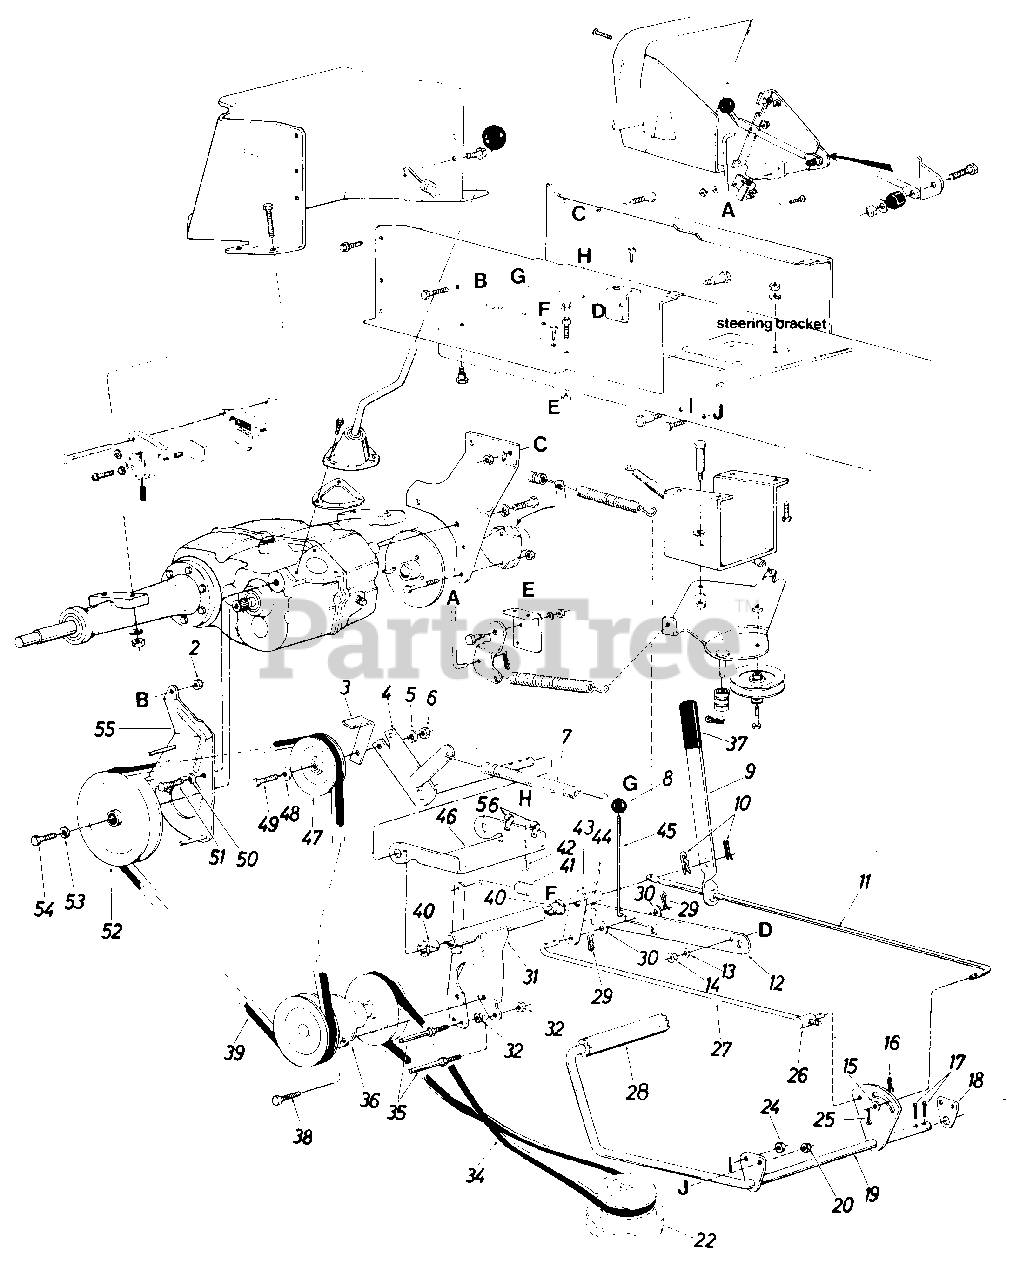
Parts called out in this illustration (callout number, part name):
2	Hex L-Nut 3/8-16 Thd.
5	L-Wash. 3/8" Scr.
6	Hex Nut 3/8-16 Thd.
7	Ext. Spring
8	Knob
9	Hand Brake Lever
10	Hairpin Cotter 3/8" Rod
11	Brake Rod
12	Parking Brake Cam
13	Fl-Wash. 5/16" Scr.
14	Hex Nut 5/16-18 Thd.
15	Fl-Wash. 5/16" Scr.
16	Hairpin Cotter 3/8" Rod
17	Cotter Pin 1/8" Dia. x 1.00" Lg.
18	Clutch Rod Brg. Brkt.
19	Clutch Brake Pedal Ass'y.
20	Hex Cent. L-Nut 3/8-16 Thd.
22	Engine Pulley 4.75 & 5.56
24	Hex Cent. L-Nut 3/8-16 Thd.
25	Cotter Pin 3/32" Dia. x .75" Lg.
26	Pivot Bushing
27	Brake Cam Rod
28	Foot Pad
29	Hairpin Cotter 3/8" Rod
30	Fl-Wash. 3/8" I.D. x 1.00" O.D. x .030
31	Jack Shaft Mtg. Brkt. Ass'y.
32	Hex Top L-Nut 3/8-16 Thd.
34	"V"-Belt 1/2 x 59" Lg. (Polyester)
35	Stud 3/8-16 x 3.62" Lg. Special
36	Jack Shaft Ass'y.
37	Flat Grip
38	Hex Sem Scr. 5/16-18 x .75" Lg.
39	"V"-Belt 1/2 X 40" Lg. (Kevlar)
40	Nyliner 5/8" I.D. x .88" Lg.
41	Ext. Spring
42	Hex Thd. Rolling Scr. 1/4-20 x .50" Lg.
43	Clutch-Idler Horn Ass'y.
44	Spring Pin Spiral 1/4" Dia. x 1.00" Lg.
45	Parking Brake Link
46	Idler Mtg. Brkt. Drive
47	4" "V"-Idler Pulley
48	Fl-Wash. 3/8" I.D.
49	Hex Scr. 3/8-16 x 1.75" Lg.
50	L-Wash. 3/8" Scr.
51	Hex Scr. 3/8-16 x .75" Lg.
52	"V"-Pulley 7.0" O.D.
53	L-Wash. 3/8" I.D.
54	Hex Scr. 3/8-24 x .75" Lg.
55	Belt Guard Ass'y.
56	Plastic Hose Clamp
